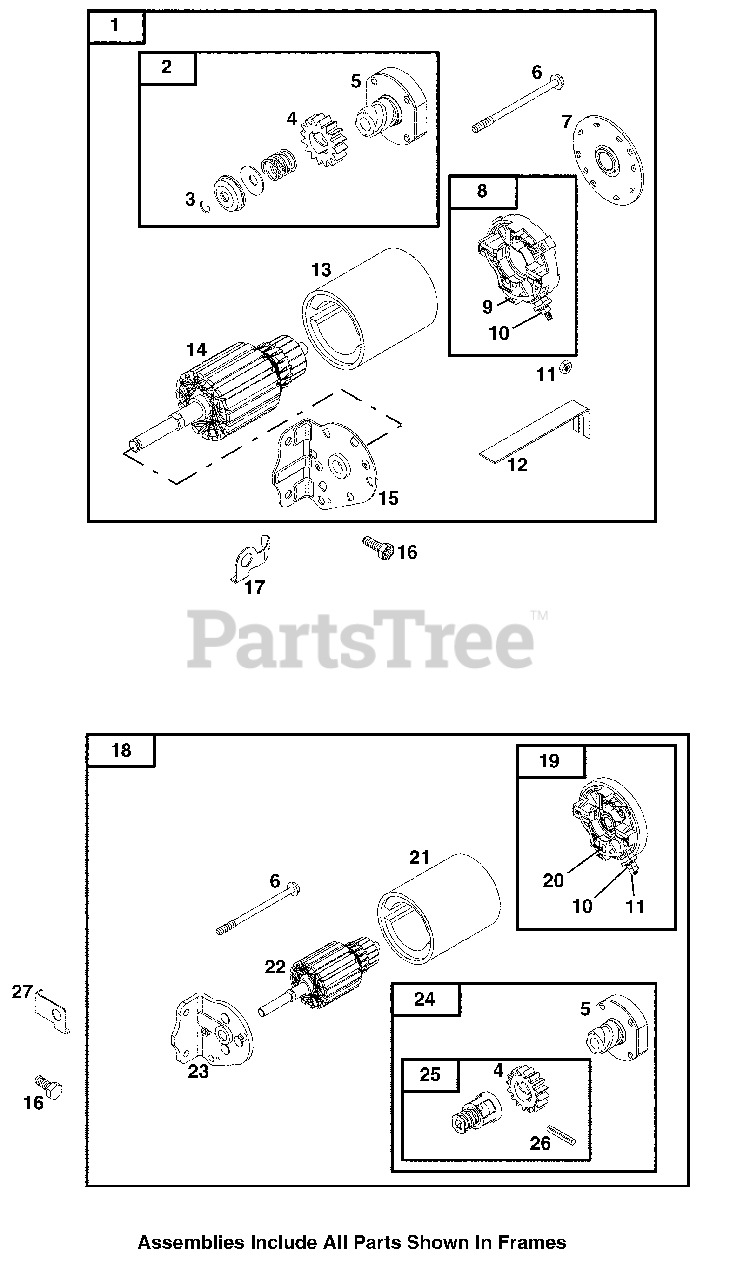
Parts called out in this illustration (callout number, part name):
1	Motor-Starter
2	Drive-Starter
3	Ring-Retaining
4	Gear-Pinion
5	Clutch-Drive
6	Bolt
8	Retainer-Brush
10	Nut
11	Nut
12	Starter Strap
13	Housing-Starter
14	Armature-Starter
15	Cap-Drive
16	Screw(Drive Cap)
21	Housing-Starter
22	Armature-Starter
24	Drive-Starter
25	Kit-Gear
26	Pin-Roll
